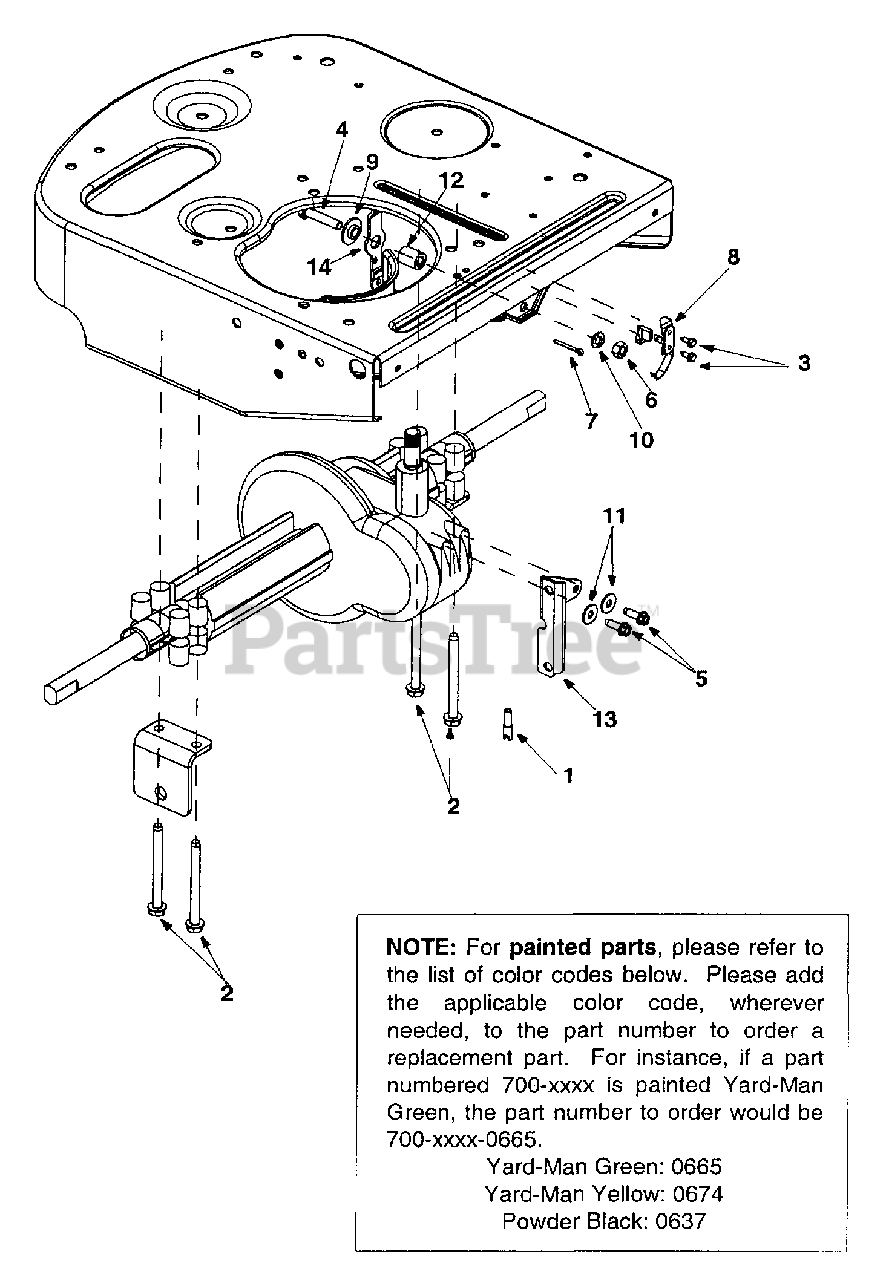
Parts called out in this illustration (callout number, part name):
1	Harness Assembly Adapter
2	Hex TT Screw 5/16-18 x 3.50
3	Hex Washer Head Self-Tap. Screw
4	Hex Screw 5/16-18 x 1.5 Gr. 5
5	Thd. Forming Scr. 1/4-20 x .75
6	Hex Nut 5/16-18
7	Cotter Pin
8	Insulator Nut Plate
9	Shoulder Bushing
10	Lock Washer 5/16
11	Flat Washer .28 I.D. x .74 O.D. x .083
12	Spacer
